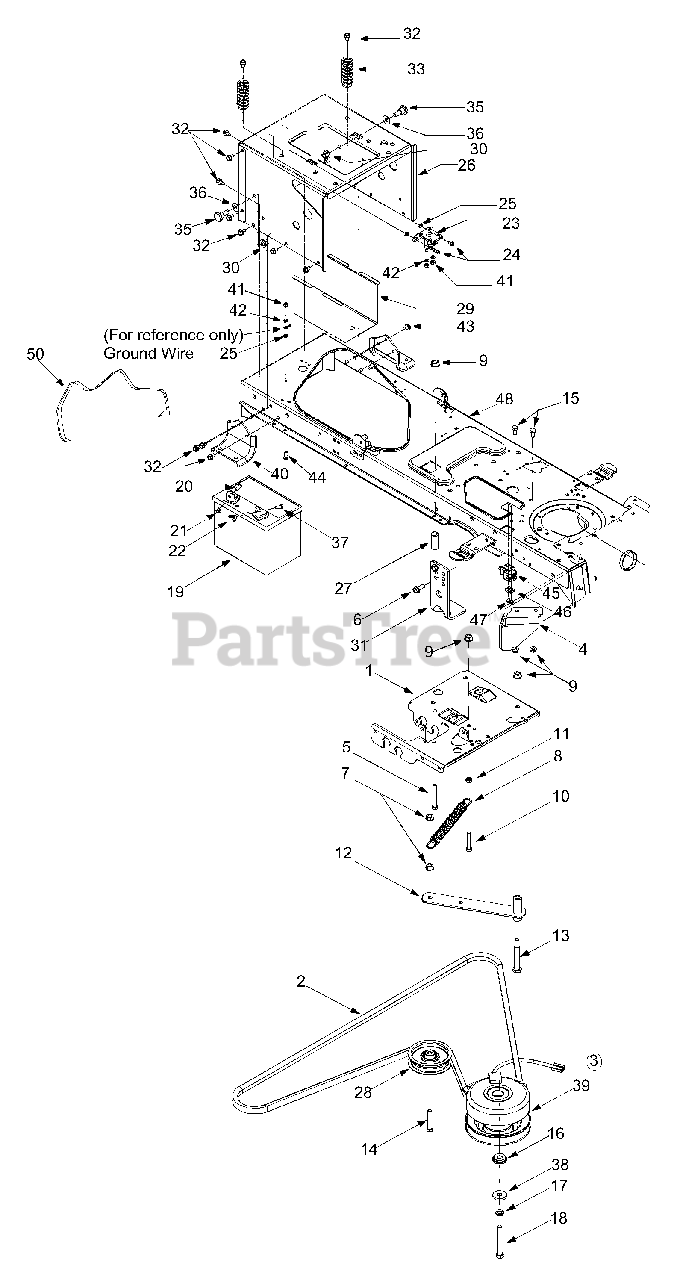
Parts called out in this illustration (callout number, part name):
2	PTO Belt (two belt deck design)
3	Elec. PTO Clutch
3	Washer, Flat 1.031 x 1.62 x .095
6	Hex Hd Wash. Screw, 5/16-18 x .875
7	Lock Nut, 3/8-16
8	Extension Spring, .62 x 5.62
9	Flange Lock Nut, 5/16-18
10	Hex Cap Screw, 5/16-18 x 1.75
11	Hex Nut, 5/16-18
14	Hex Cap Screw, 3/8-16 x 2.0
15	Hex Cap Screw, 5/16-18 x .625
16	Shoulder Spacer, 1.38 x .445 x .36
17	Lock Washer, 7/16
18	Hex Cap Screw, 7/16-20 x 3.25
19	12-volt Battery, 270 CCA
20	Carriage Screw 1/4-20 x 0.75
21	Hex Sems Nut, 1/4-20
22	Wing Nut, 1/4-20
23	Solenoid, 12-Volt, 100 Amp
24	Self Tapping Screw, 1/4-20 x .5
25	Lock Washer, 1/4
28	Idler Pulley, 3.5
32	AB Screw, 5/16-12 x .75
33	Compression Spring
35	Shoulder Screw, .625 x .5, 7/16-20
36	Bell Washer, .45 x 1.0 x .062
37	Shoulder Screw, 1/4-20, .25 x .15
38	Flat Washer, .45 x 1.25 x .164
39	Harness Assembly, PTO Clutch
41	Hex Nut 1/4-20
42	Lock Washer
43	TT Screw 5/16-18 x 0.5
44	TT Screw 1/4-20 x 0.75
45	Switch
46	Switch Plate
47	AB Screw #10-16 x 0.5
49	Lock Nut 3/8-16
50	Battery Hold-Down Rod
